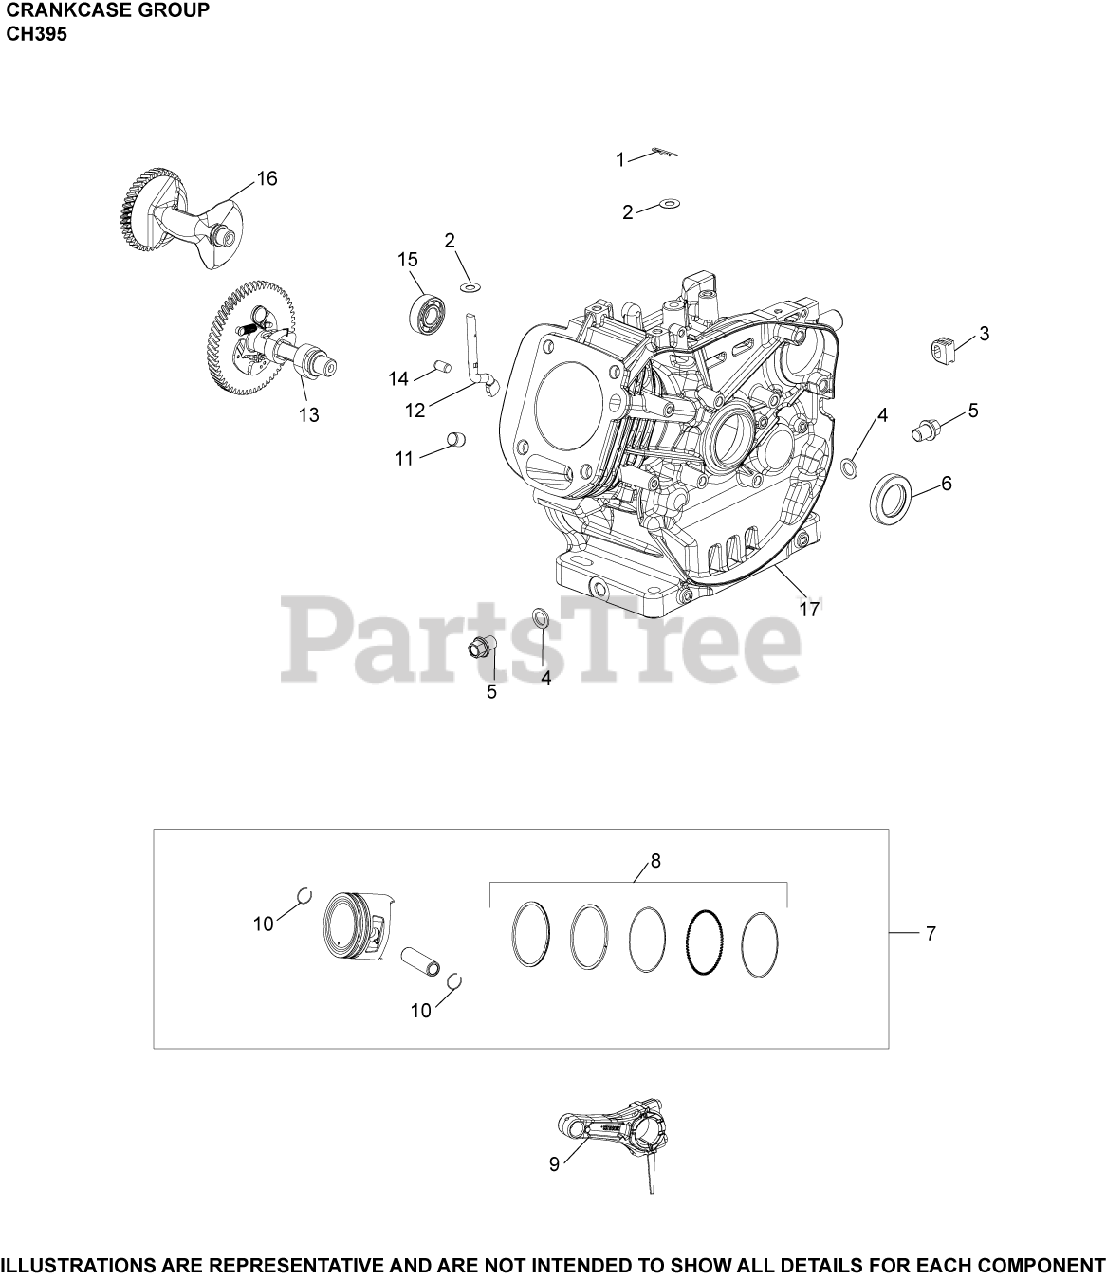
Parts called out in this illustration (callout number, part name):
1	CLIP, GOVERNOR SHAFT
2	WASHER, FLAT
3	GROMMET, CRANKCASE
4	WASHER, DRAIN PLUG
5	KIT, DRAIN PLUG
6	SEAL, RADIAL SHAFT
7	KIT, PISTON - (#1787406S)
7	KIT, PISTON (0.25 O.S.) - DISCONTINUED
8	RING SET (STD), TOP RING 2 mm (.079") USE 17 874 06-S
8	RING SET (STD), TOP RING 1.48 mm (.058")
9	ROD, CONNECTING ASSEMBLY
10	RETAINER, PISTON PIN
11	PIN, DOWEL CYLINDER HEAD
12	SHAFT, GOVERNOR CROSS
13	CAMSHAFT ASSEMBLY
14	PIN, DOWEL
15	BEARING, BALANCE SHAFT
16	SHAFT, BALANCE
17	CRANKCASE
